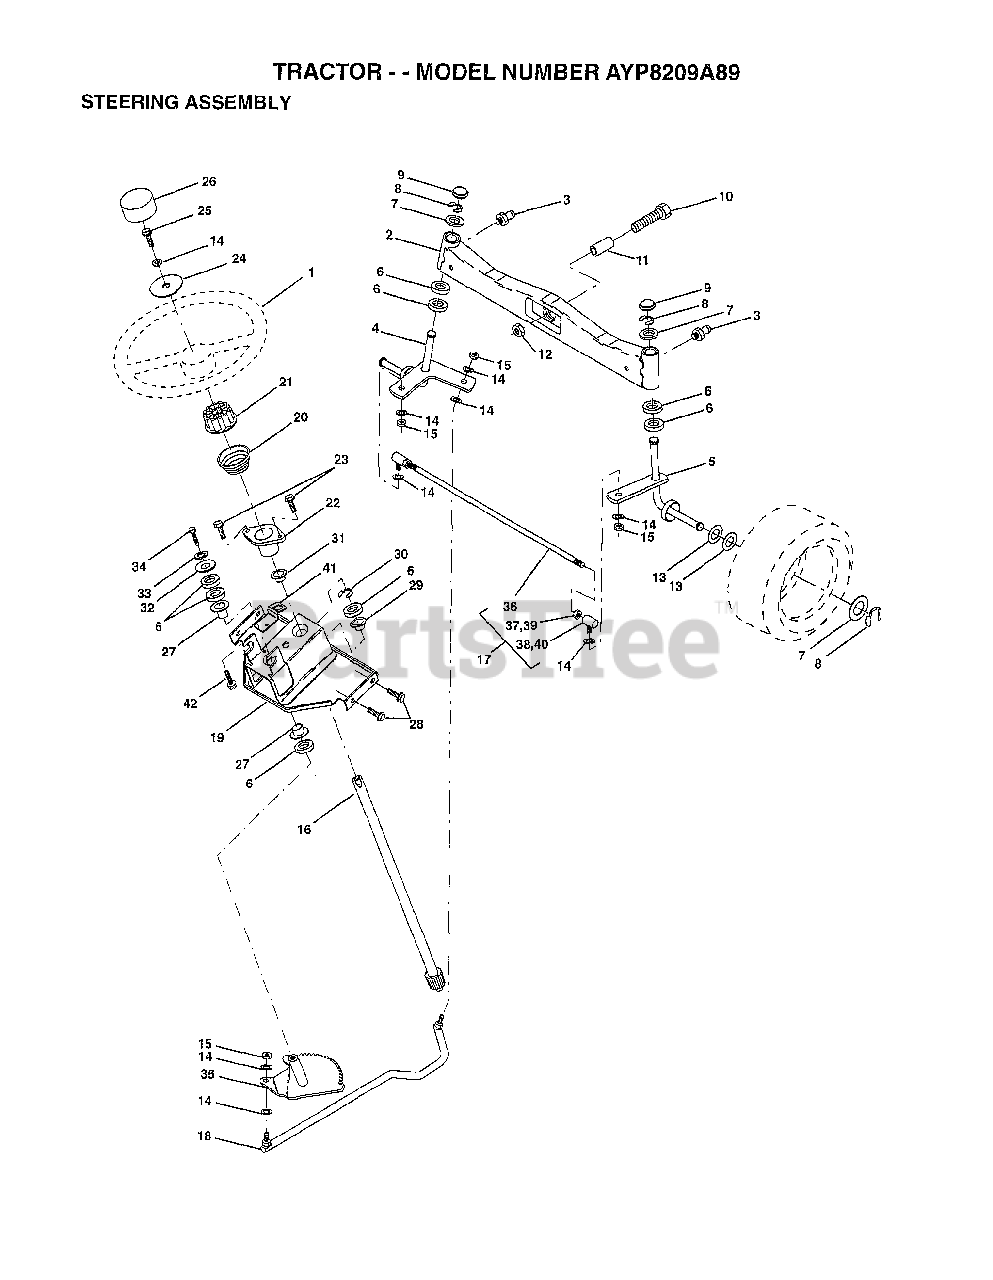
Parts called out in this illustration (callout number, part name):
3	ZERK M
4	SPINDLE ASM LH
5	SPINDLE ASM RH
6	WASHER .T
7	WASHER
8	RING
9	CAP
10	BOLT
11	SPACER BEARING
12	"NUT-LOC,FLANGE LT"
13	WASHER
14	LOCKWASHER
15	GRIPCO NUT
16	SHAFT.STEER.VGT
17	ROD.ASM.TIE.BALL
18	DRAGLINK.BALL.JOI
19	SUPPORT ASM-STEER
21	ADAPTER LT
22	"BUSHING,STEERING"
23	"SCREW-TT,10-32 FL"
24	WASHER T
25	BOLT
26	"INSERT,STR WHEEL"
27	COL. SRTG. BEAR.
28	SCREW
29	"FLANGE GT, BEAR."
30	KLIP RING
31	BUSHING.NYLINER.
32	WASHER
33	LOCKWASHER
34	BOLT
35	GEAR.ASM.SECTOR.
37	NUT
38	JOINT.RH
39	NUT
40	JOINT.LH
41	"BRKT-SW, INTER"
